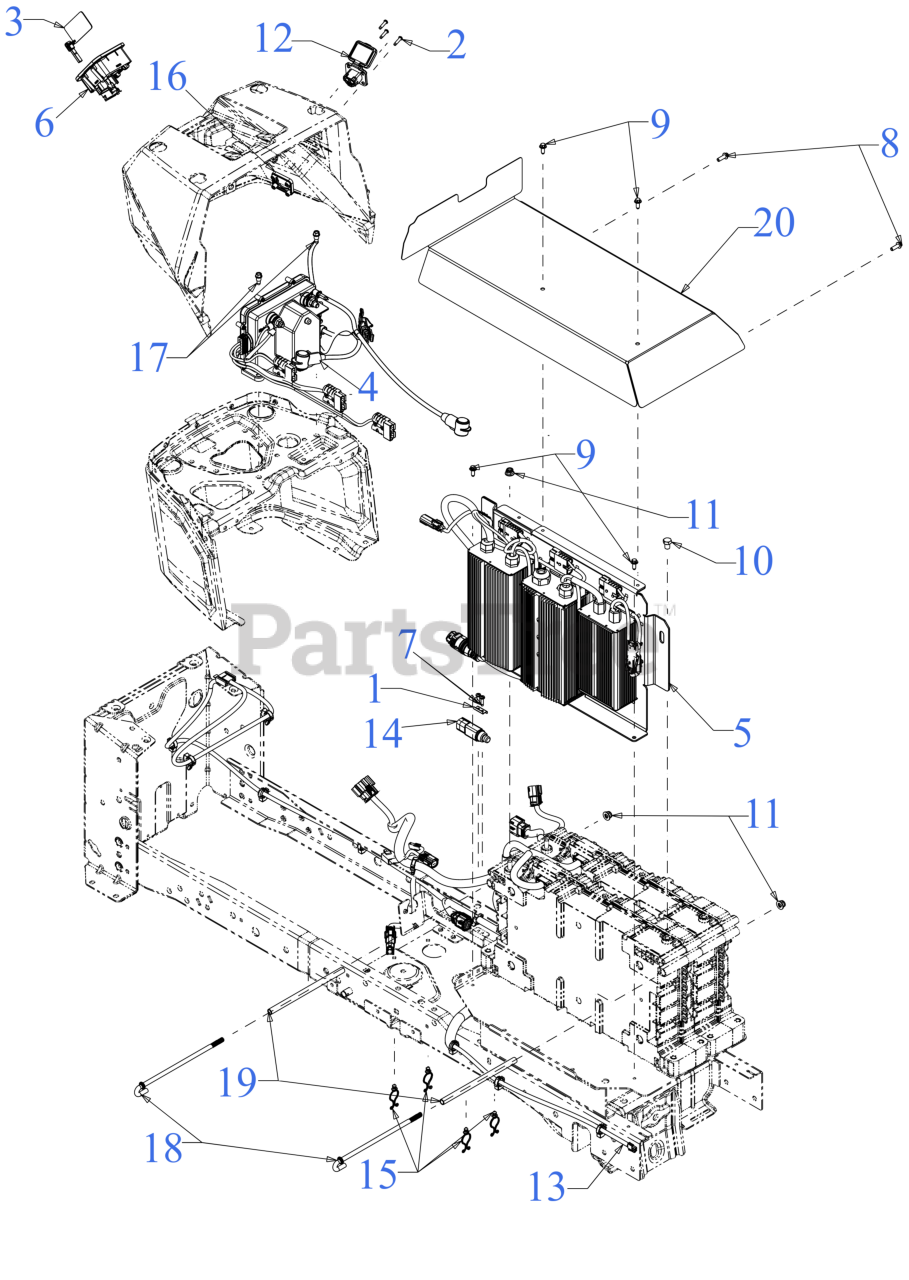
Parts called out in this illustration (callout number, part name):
1	PLATE-SWITCH
2	SCREW, #8-16X.750 PH
3	MAGNETIC KEY
4	PDM HOUSING ASSEMBLY
5	MOTOR PANEL
6	VCM SWITCH (UL G2)
7	SCREW #10-24X11/16 T-25
8	SCREW 1/4 x .750
9	SCREW M6-1 x .625
10	SCREW 3/8-24 x .50" GR5 STD
11	FLANGE LOCK NUT 5/16-18
12	CHARGER PORT HARNESS (8-PIN)
13	HARNESS (VCM/PDM/GEN2)
14	SEALED PLUNGER SWITCH
15	TWIST LOCK CLIP
16	CHARGING PORT ADAPTER
17	SHOULDER SCREW
18	BATTERY ROD
19	SPACER- .322" x .438" x 7.71"
20	BATTERY COVER BRACKET
20	BATTERY COVER
